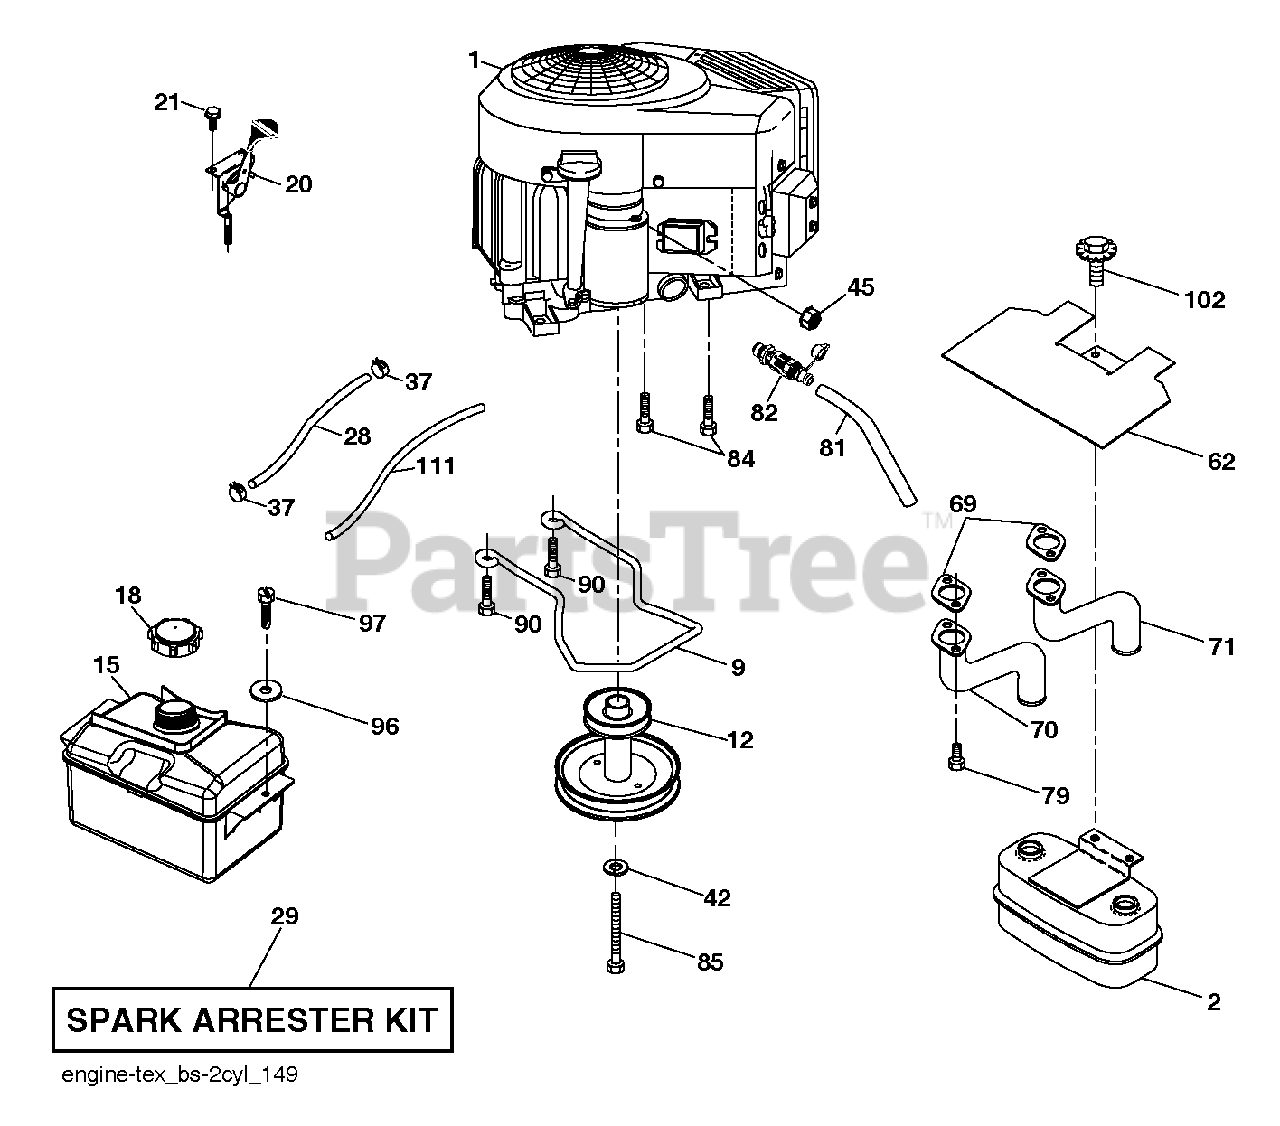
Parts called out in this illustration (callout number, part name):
2	MUFFLER.ASM.TWN.EXTNDED.DFLCTR
9	KEEPER.BELT.ENG.4.25"2.BLT.431
12	PULLEY.ENGINE
15	TANK.ASM.FRT.2.5 GAL.W/CAP.EPA
18	CAP.FUEL.2 WAY VENT
20	THROTTLE.COBRA.38"READSTART.BK
21	SCREW.#10 X 0.750.BOS
28	LINE.FUEL.20"FRONT.EMI
29	KIT.SPARK ARRESTOR 794945 B&S
37	HOSE CLAMP
42	LOCKWASHER
45	NUT
62	SHIELD.HEAT.MUFFLER
69	GASKET.MUFFLER
70	EXHAUST.TUBE.LH.BS/TWIN
71	EXHAUST.TUBE.RH.B&S.TWIN.INTEK
79	SCREW.SOCKET.HEAD.5/16-18
81	TUBE, DRAIN OIL ASM.
82	VALUE.OIL.DRAIN
84	SCREW.3/8-16
85	BOLT HEX 7/16-20X4-1/4"
90	SCREW 3/8-16X1
96	WASHER
97	SCREW HEXWSHR 1/4-20X3/4
102	SCREW
111	RP PURGE LINE
